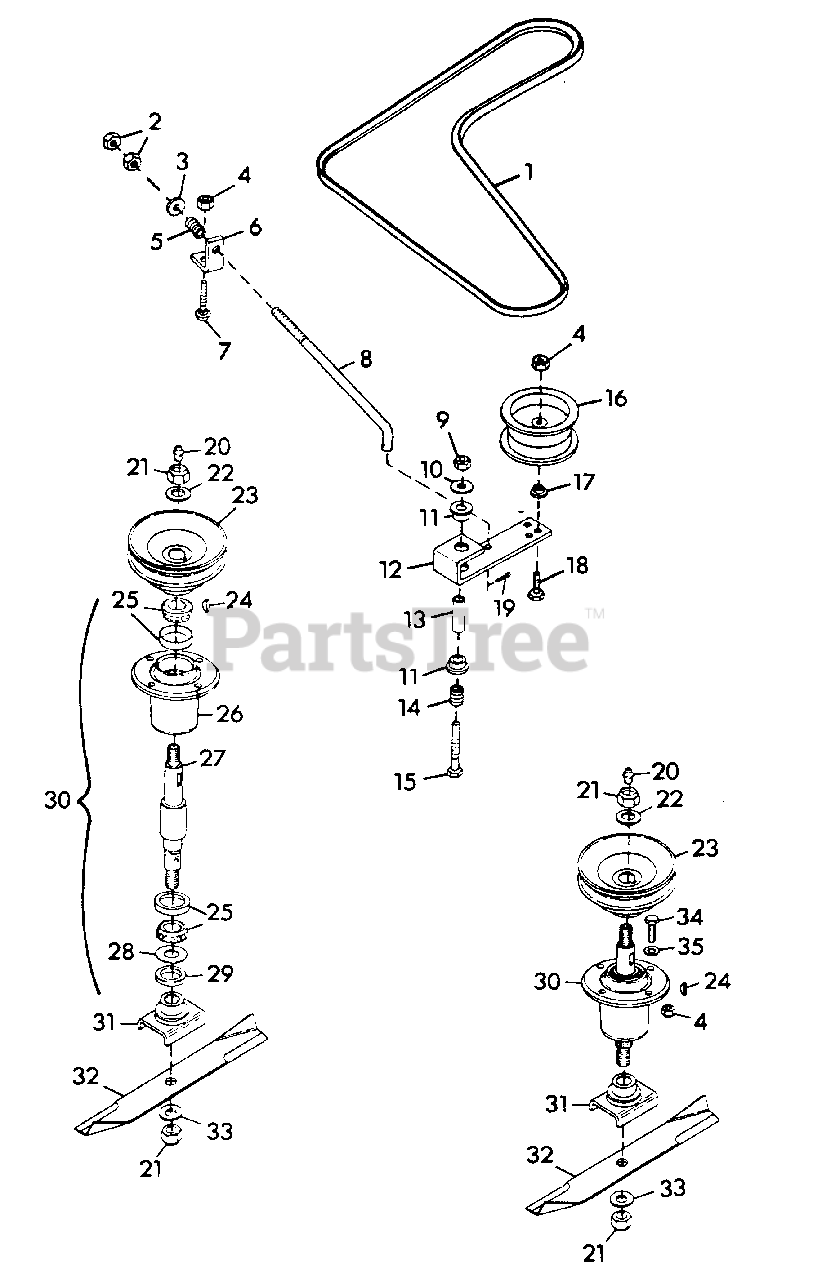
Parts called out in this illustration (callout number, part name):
1	Belt, Pro-36 Mower
2	Nut, Hex 3/8-24
3	Washer, Flat .406x.812x.065
4	Nut, Lock 3/8-16
5	Spring, Compression 1x.78x338
6	Bracket, Belt Tensioner
7	Bolt, Hex 3/8-16x.875
8	Rod, Idler
9	Nut, Lock 1/2-13
10	Washer, Flat .531x1.250x.100
11	Bushing, Nylon .76x1.00x.600 Flg.
12	Arm, Idler Pivot
13	Spacer
14	Spring, Compression 1x.80x36
15	Bolt, Hex 1/2-13x3.25
16	Pulley, Idler
17	Bushing
18	Bolt, Hex 3/8-16x2.25
19	Pin, Cotter .09x.75
20	Fitting, Lube 1/8
21	Nut, Lock 5/8-11
22	Washer, Flat .687x1.312x.122
23	Sheave, Spindle
24	Key, Woodruff 1/4x1 Hard #15
25	Assembly, Bearing
26	Housing, Bearing
27	Shaft, Spindle
28	Washer, Flat .975x1.970x.030
29	Seal, Steel
30	Assembly, Spindle
31	Weldment, Blade Cradle
32	Blade, 36" Mower
33	Washer, Flat .656x1.312x.095
34	Bolt, Hex 3/8-16x1.25
35	Washer, Flat .438x1.00x.083
